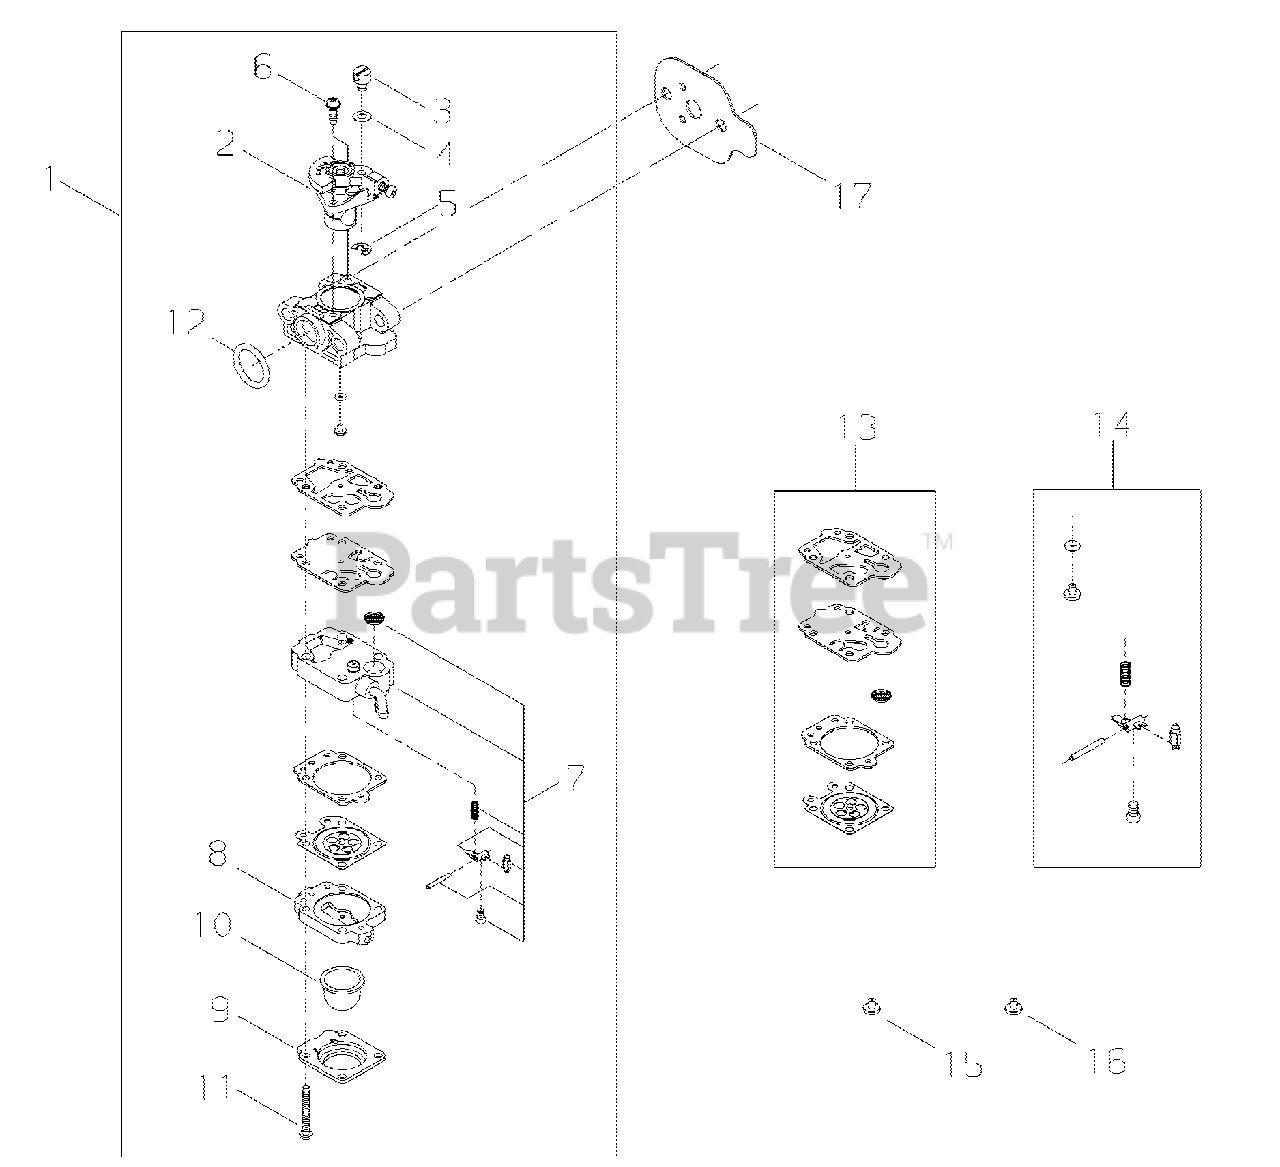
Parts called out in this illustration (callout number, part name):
1	CARBURETOR
2	THROTTLE VALVE ASSY
3	SWIVEL
4	WASHER
5	RING, RETAINING
6	SCREW
7	PUMP BODY ASSY
8	BASE, PURGE
9	RETAINER, PURGE BULB
10	BULB, PURGE
11	SCREW, PUMP COVER
12	O-RING - 15
13	DIAPHRAGM/GASKET KIT
14	INLET NEEDLE VALVE KIT
15	JET, MAIN - 1000M #40
16	MAIN JET - 2000M #39
17	GASKET, INTAKE
